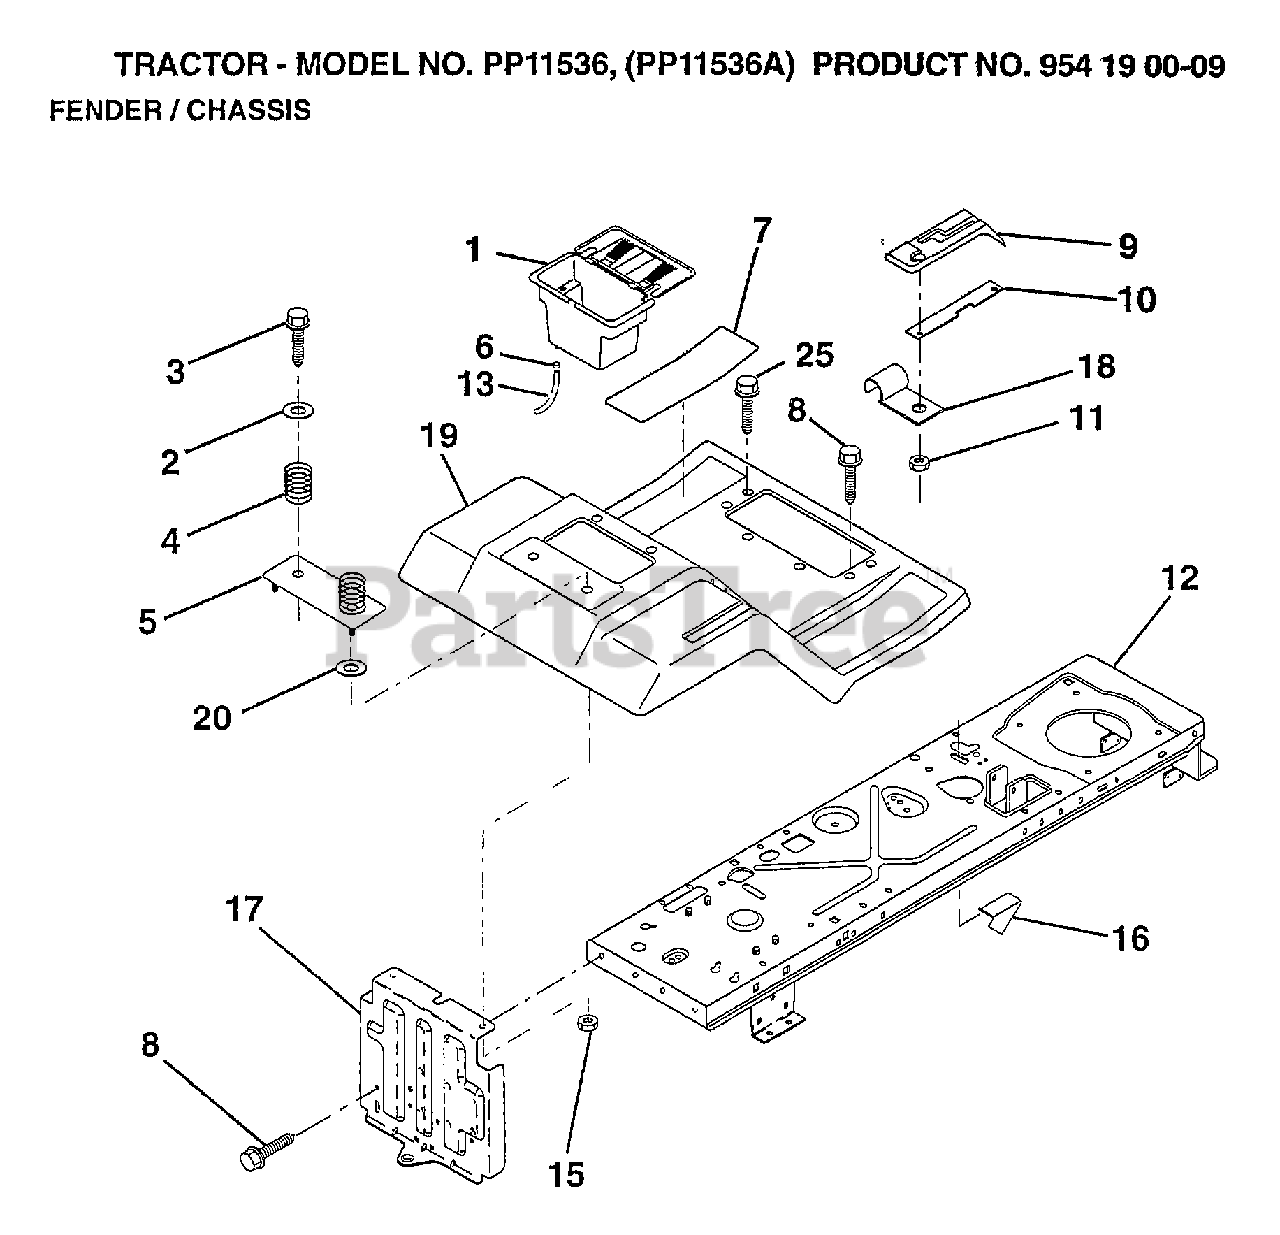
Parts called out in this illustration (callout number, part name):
1	"CASE,BATTERY.MECH"
2	WASHER
3	SCREW
4	SPRING COMPRESSIO
5	"PLATE ASM, BATT."
6	HOSE CLAMP T
7	PAD FOOTREST
8	SCREW
9	"CONSOLE,SHIFT CON"
10	PLATE LOCK SHIFT
11	NUT
12	CHASSIS.WELD.ASM.
13	TUBE T
15	NUT HXKEP 1/4X20
17	DRAWBAR ASM LR
18	"CLIP,INSULATOR"
19	FENDER/FOOTREST
25	SCREW
